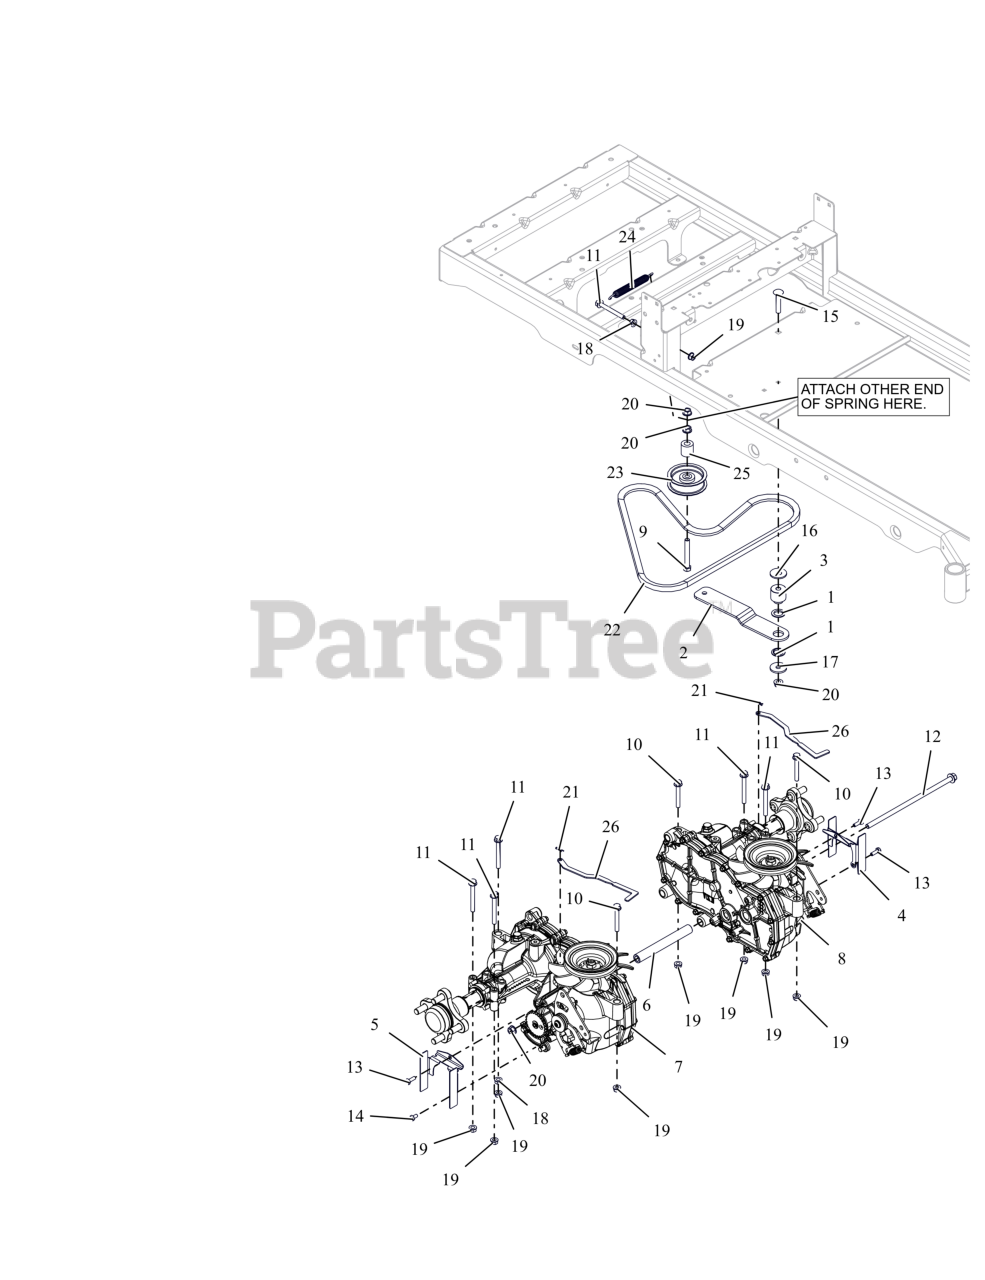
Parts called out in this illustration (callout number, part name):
1	BUSHING, IDLER ARM
2	IDLER ARM, GROUND DRIVE
3	SPACER, GROUND DRIVE IDLER
4	GUARD, PARKING BRAKE RH
5	GUARD, PARKING BRAKE LH
6	SPCR, TRANSAXLE .438 ID X .750 OD X 8.18
7	TRANSAXLE
8	TRANSAXLE
9	BLT, HEX .38-16X2.75 G5 ZCC
10	BLT,HEX-FLG .31-18X2.25 G5 ZCC
11	BLT,HEX-FLG .31-18X2.75 G5 ZCC
12	BLT, HEX-FLG 0.375-16X9.75 GR5 ZC120
13	@BLT-HEX .25-20X.75 GR5 YWZC
14	@BLT-HEX .25-20X.50 GR5 YWZC
15	BLT,RHSSN.375-16X2.00 G5 ZCC
16	WSHR,FLT .563X1.375X.109 ZCC
17	WSHR,FLT .406X1.375X.135 ZCC
18	NUT,SPNLK-FLG .31-18 G5 ZCC
19	NUT,LK-CTR-FLG .31-18 GF ZCC
20	NUT-LK-CTR-FLG .375-16 GF ZCC
21	PIN, HAIR #178 .06X.77 ZCC
22	V-BELT, HA-RAW EDGE
23	PULLEY, ENGINE CLUTCH 03608
24	SPRING, EXTENSION
25	BSHG-SLV .391X.688X.52 PM
26	BRKT, VALVE DUMP (BLACK)
